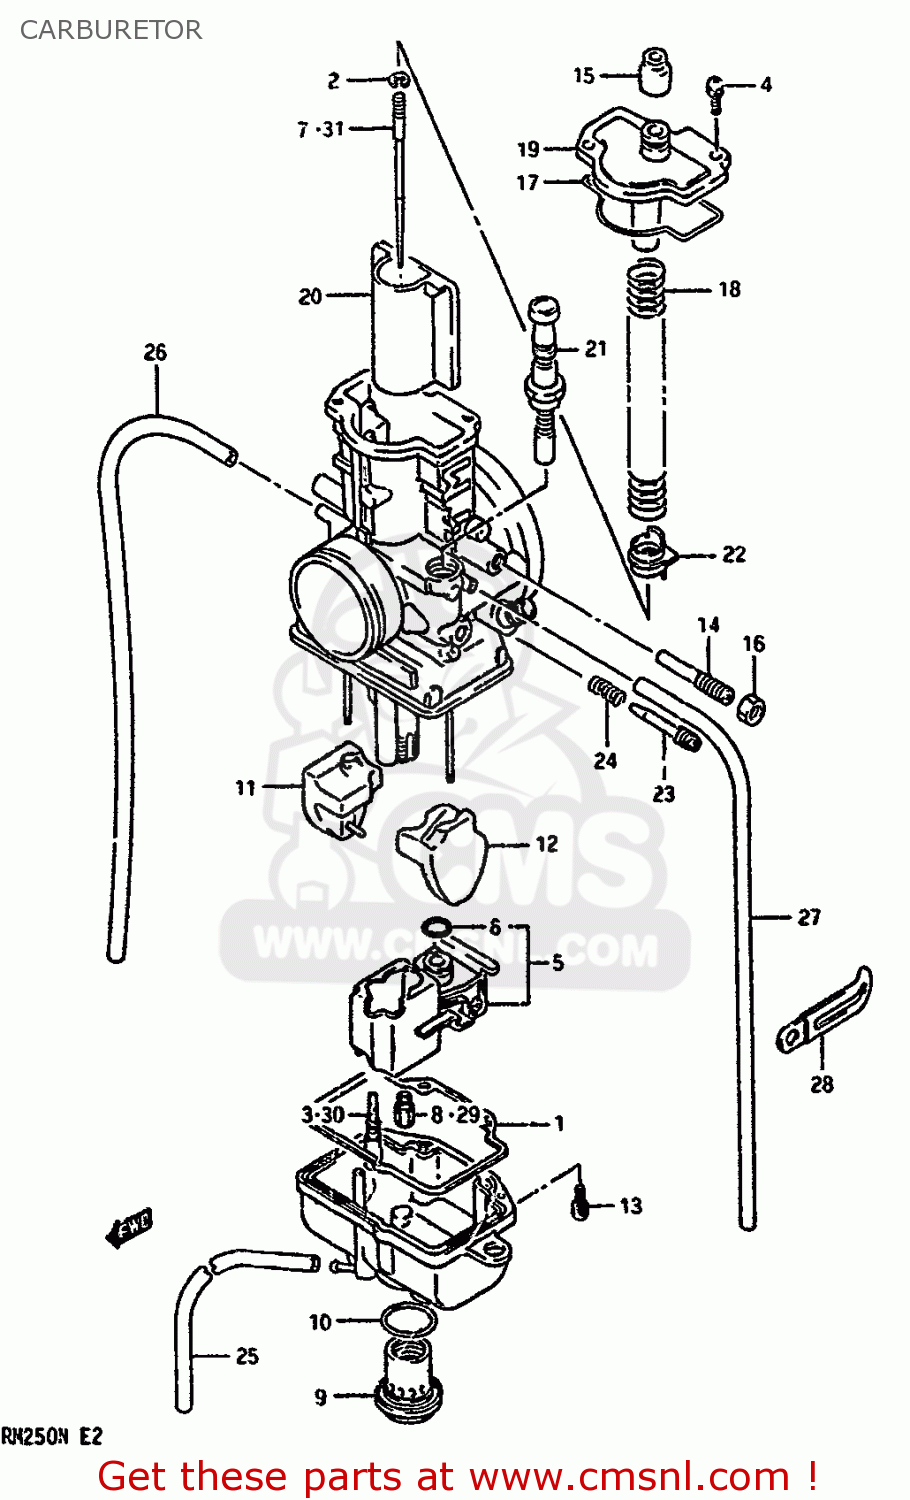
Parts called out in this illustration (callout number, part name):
1	O RING,FLOAT CHAMBER
2	CLIP,NEEDLE
3	JET,PILOT(55)
4	SCREW
5	VALVE ASSY,NEEDLE
6	O-RING,NEEDLE VALVE
7	NEEDLE JET
8	JET,MAIN(370)
9	CAP,DRAIN
10	O RING
11	FLOAT,R
12	FLOAT,L
13	SCREW
14	ADJUSTER
15	CAP
16	NUT
17	O RING,TOP CAP
18	SPRING
19	CAP,TOP
20	VALVE,PISTON(CA:3.5)
21	PLUNGER ASSY
22	RING
23	SCREW,AIR
24	SPRING
25	HOSE(3X5X600)
26	HOSE(3.5X6.5X600)
27	HOSE(3.5X6.5X600)
28	CLAMP
29	JET,MAIN(330)
30	JET,PILOT(35)
31	NEEDLE JET
